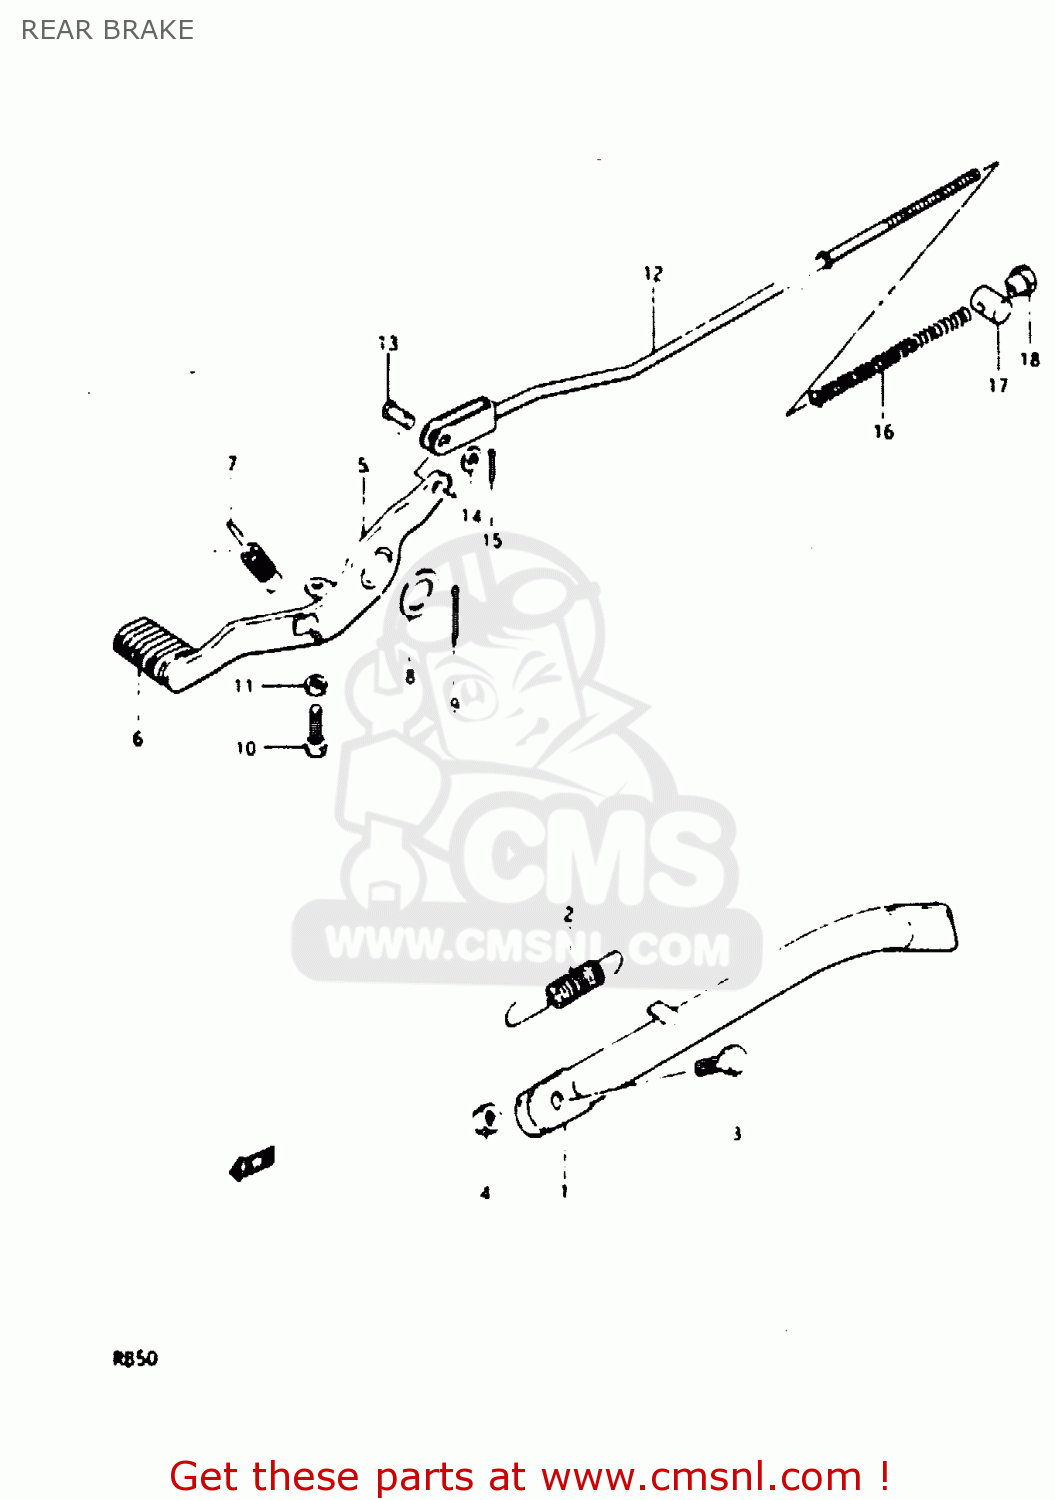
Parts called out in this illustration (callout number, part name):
2	SPRING
3	BOLT(8X25)
4	NUT
5	PEDAL,BRAKE
6	RUBBER,PEDAL
7	SPRING
8	WASHER (15X24X1.6)
9	COTTER PIN
10	BOLT
11	NUT 6MM
12	ROD ASSEMBLY,REAR BRAKE
13	PIN(L:13.5)
14	PIN 20X20
15	WASHER
16	SPRING
17	PIN
18	NUT (6MM)
